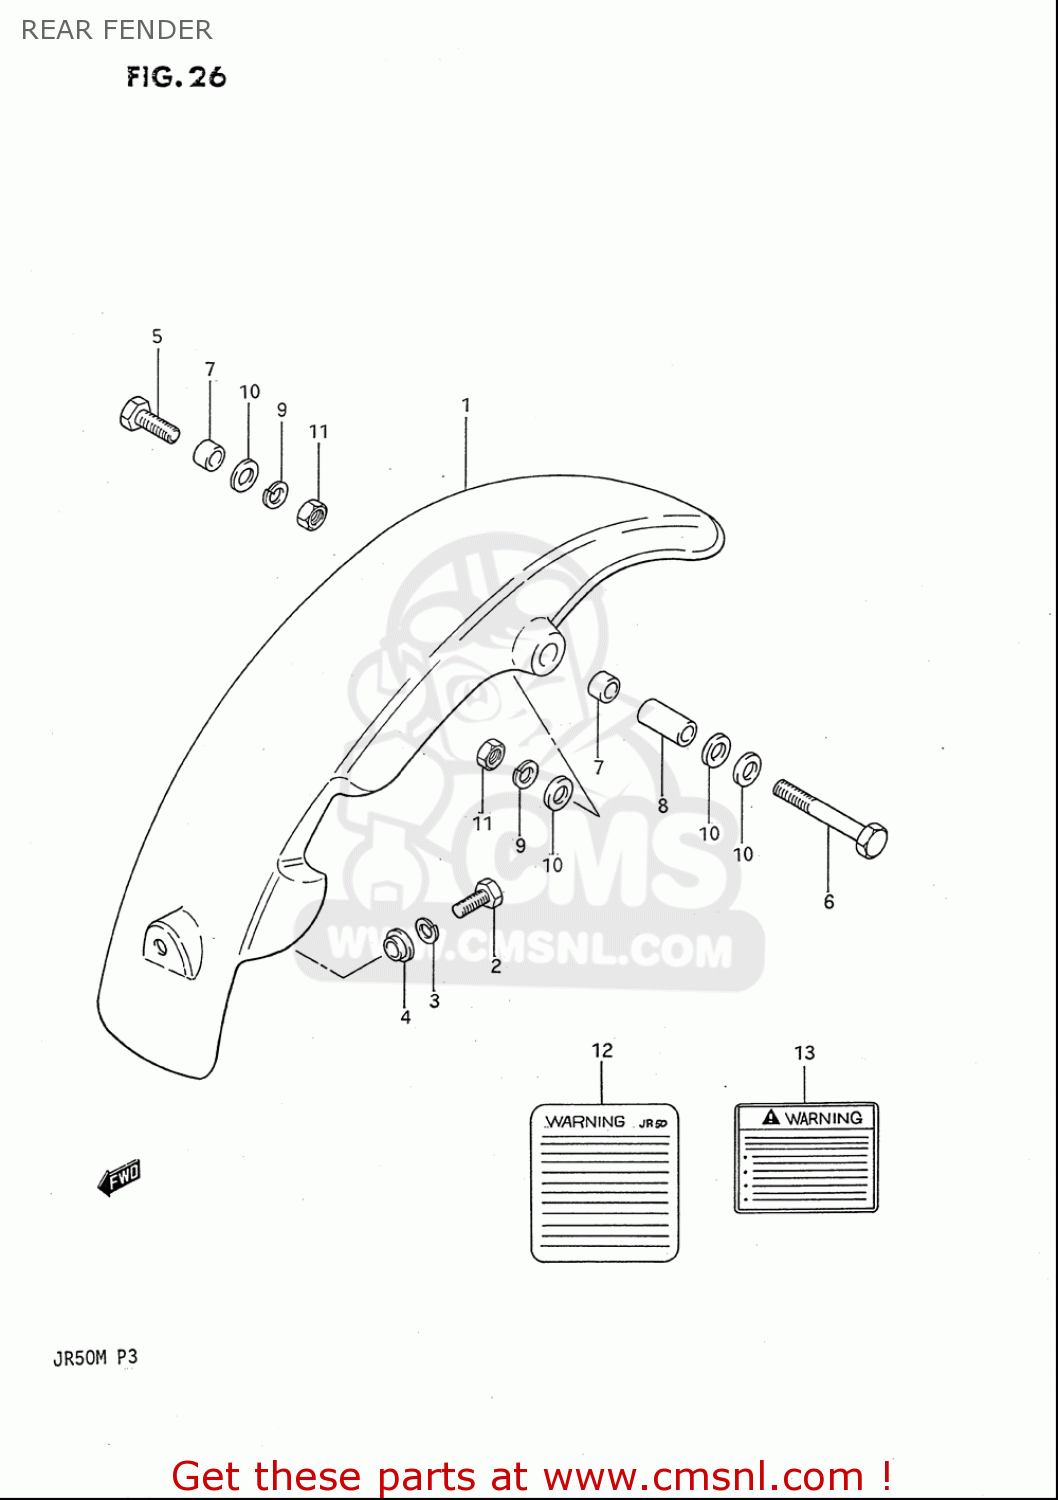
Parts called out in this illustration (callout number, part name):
1	FENDER,RR
2	BOLT
3	WASHER,LOCK
4	WASHER
5	BOLT
6	BOLT
7	SPACER,RR FENDER RR
8	SPACER (8.2X12.5X23.5)
9	WASHER,LOCK
10	WASHER
11	NUT
12	LABEL,WARNING
13	LABEL,GENERAL WARNING
